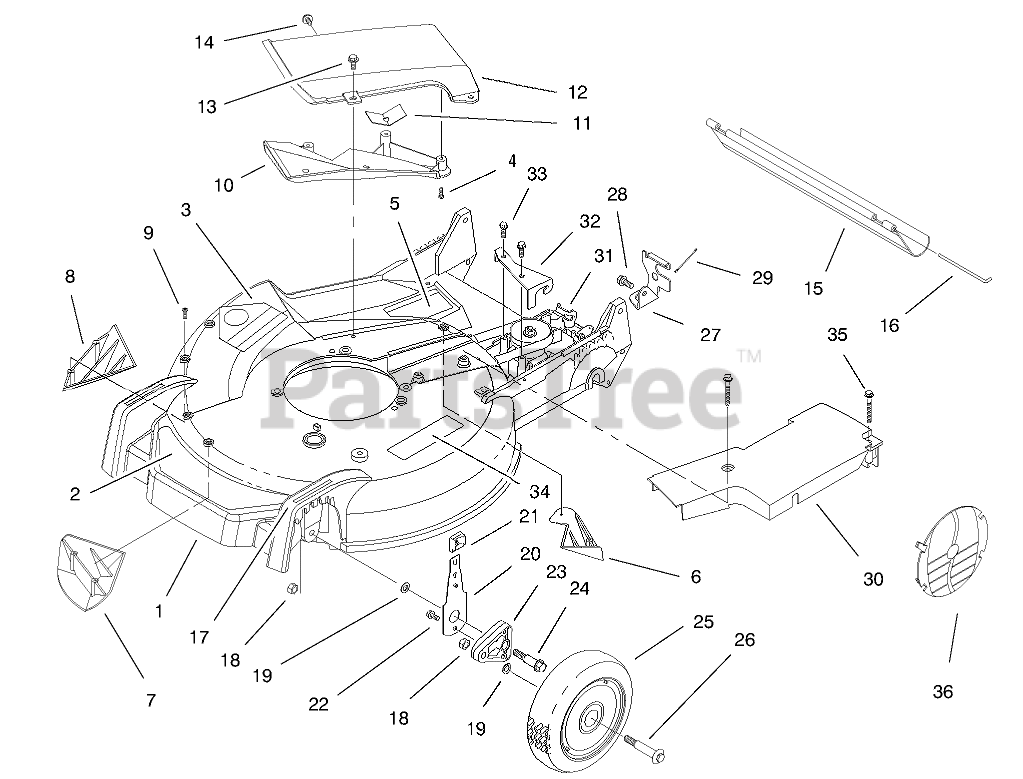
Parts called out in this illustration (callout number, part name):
1	Housing-21" (Incl. Ref. #3, 5-9 pg. 1, 34 pg. 2)
2	DECAL - DECK
3	DECAL-DANGER
4	Screw-PPH
5	DECAL - DANGER
6	KICKER-REAR
7	KICKER-FRONT
8	KICKER-RH
9	SCREW-PPH
10	Deflector-Recycler
11	Guard-Cover
12	Cover-Recycler (Incl. Ref. #4, 10, & 11)
13	SCREW-HWH
14	SCREW AND WASHER ASM
15	SHIELD-TRAILING
16	ROD-SHIELD
17	DECAL - HOC
18	NUT-LOCK
19	WASHER
20	FRONT SPRING ARM ASM
21	KNOB-ARM
22	SCREW-HWH
23	ARM-PIVOT, FRONT
24	BOLT-SHOULDER
25	WHEEL AND TIRE ASM
26	BOLT-WHEEL
27	Bracket-Adj. Trac
28	SCREW-HWHTF
29	RETAINER-CABLE
30	BELT COVER
31	GEARCASE ASM
32	Bracket-Guide
33	SCREW-HWHTF
34	DECAL-WARNING
35	SCREW-HHFTF
36	WHEEL COVER
